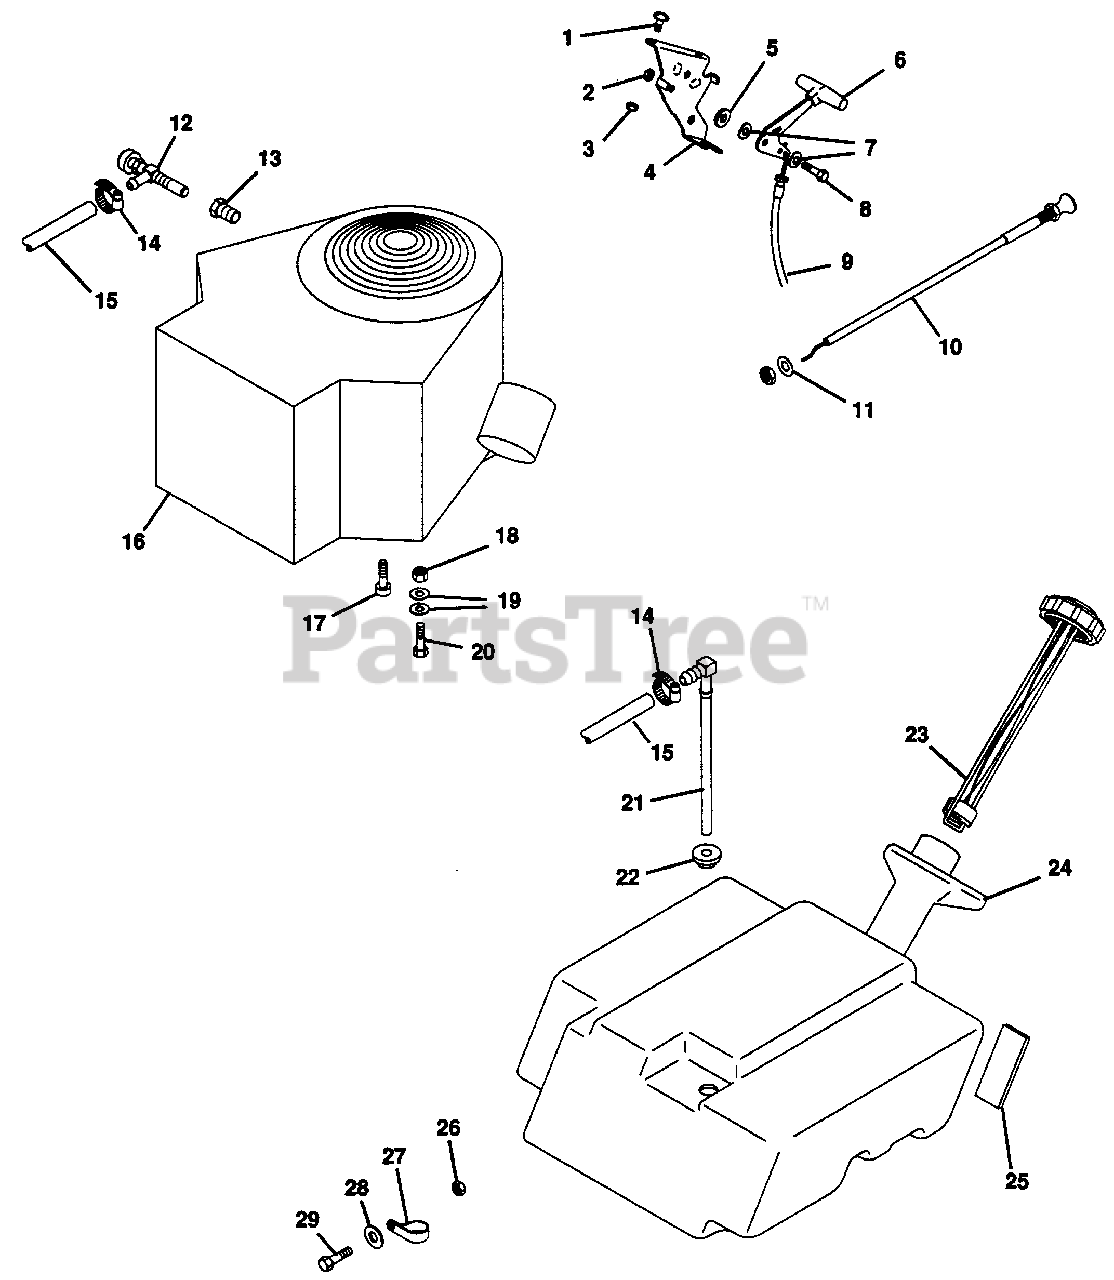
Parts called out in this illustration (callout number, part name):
1	Screw, Mach. 10-24 x .625 PHD
2	Nut, Lock 1/4-28
3	Nut, Lock 10-24
4	Bracket, Mounting L.H.
5	Washer, Flat .281 x .625 x .065
6	Assembly, Knob and Lever
7	Washer, Spring
8	Bolt, Hex 1/4-28 x .625
9	Assembly, Conduit
10	Control, Choke
11	Washer, Flat .406 x .812 x .065
12	Cock, Oil Drain
13	Adaptor, Oil Drain
14	Clamp, Hose
15	Line, Fuel .5 OD x .25 ID
16	Engine, 16 HP B & S
17	Screw, M8 x 1.25 x 20mm SOC HD
18	Nut, Lock 5/16-18
19	Washer, Flat .344 x .688 x .065
20	Bolt, Hex 5/16-18 x 1.75
21	Fitting, Tank
22	Bush., .563 x 1.06 x .688
23	Fuel Gage and Cap
24	Tank, Fuel
25	Pad, Gas Tank
26	Nut, Lock 5/16-18
27	Clamp, Steel .625
28	Washer, Flat .313 x .875 x .065
29	Bolt, Hex 5/16-18 x 1.00
